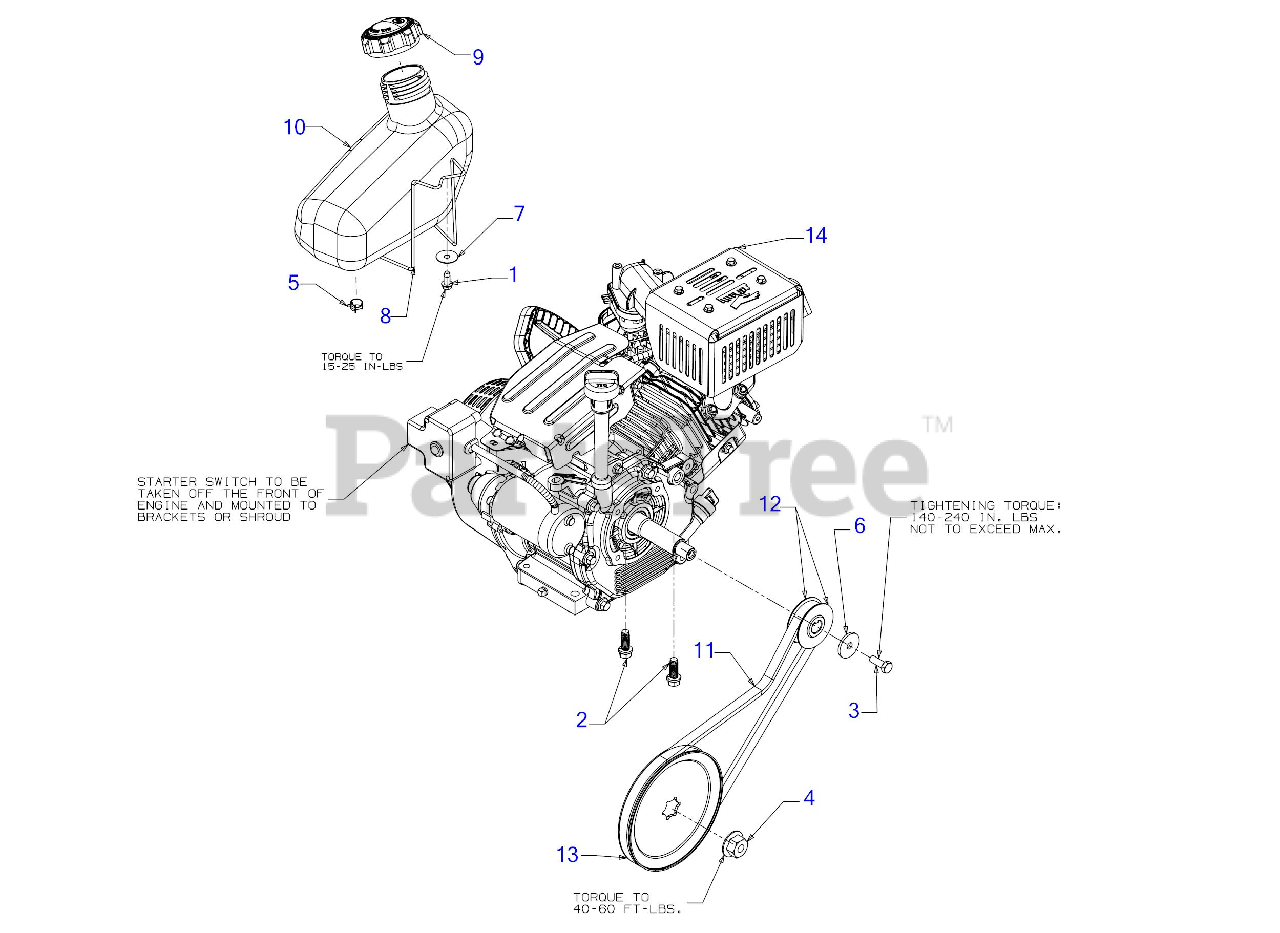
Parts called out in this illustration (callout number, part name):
1	SCREW 1/4-10:.625
2	SCREW 3/8-16 x 1
3	SCREW 5/16-24 x .875 GR5
4	FLANGE NUT W/HUB
5	HOSE CLAMP 1/20
6	WASHER-5/16 x 1.25X 1.27
7	FLAT WASHER
8	SUPPORT WIRE
10	FUEL TANK (2 QT)
11	V-BELT .500 x 35.
12	HALF PULLEY
13	AUGER PULLEY
14	208CC COMPLETE ENGINE
